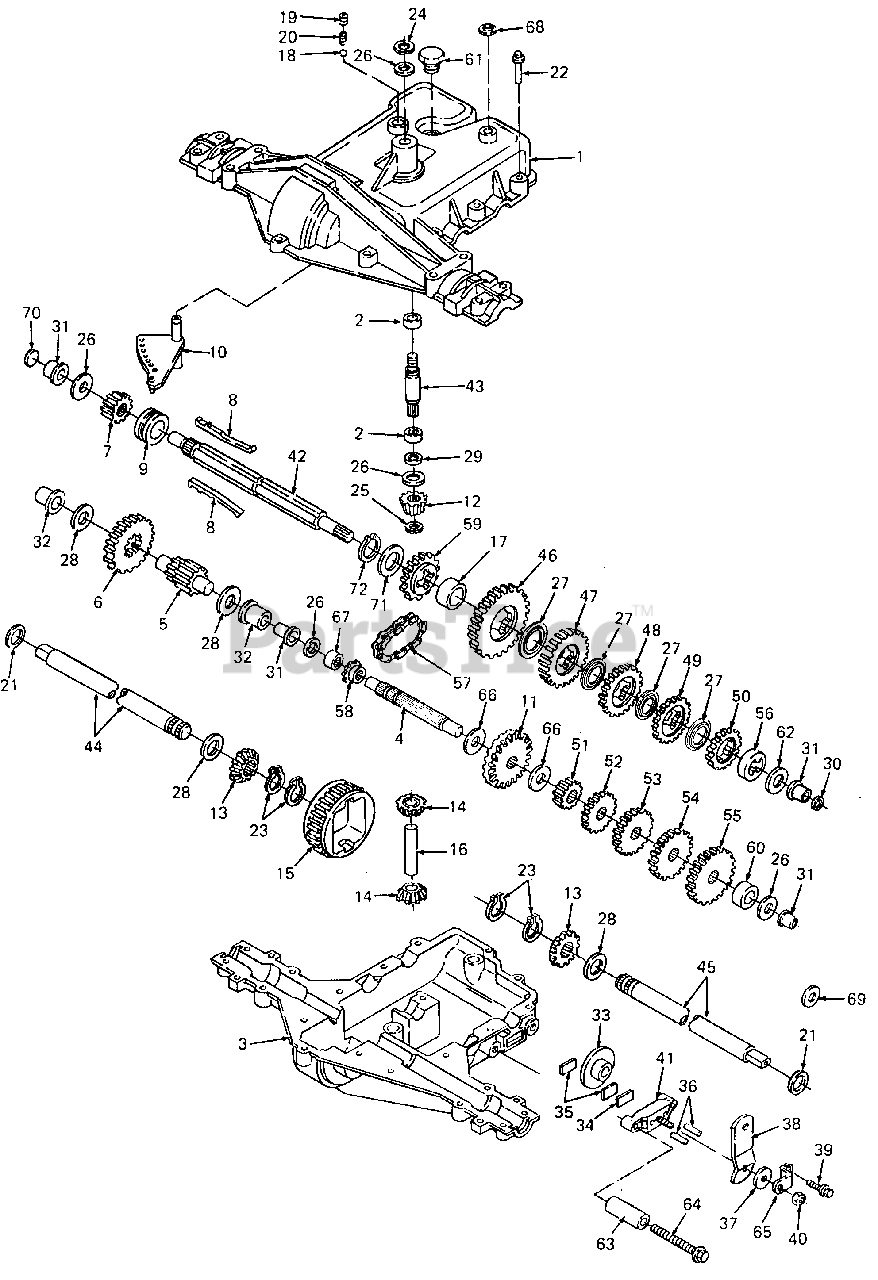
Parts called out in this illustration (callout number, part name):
1	Cover, Transaxle
2	Bearing, Needle
3	Case, Transaxle
4	Shaft, Counter
5	Shaft & Pinion Assy, Output
6	Gear, Output
7	Gear, Spur (15 Teeth)
8	Key, Shifter
9	Collar, Shifter
10	Rod & Fork Assy, Shift
11	Gear, Bevel (42 Teeth)
12	Gear, Bevel Input
13	Gear, Bevel
14	Gear, Bevel Pinion
15	Gear, Ring
16	Pin, Drive
18	Ball, 5/16 Dia, Grade 200
21	Ring, Seal
22	Screw, Flanged Hex, 1/4-20 X 1.25 Lg
23	Ring, Retainer (Set of 2)
24	Ring, Retaining
25	Ring, Ext Ret, .521
26	Washer, Thrust
29	Ring, Quad
30	Ring, Sq Cut
31	Bushing, Flanged
33	Brake, Disc
34	Plate, Brake Pad
35	Pad, Brake
36	Pin, Dowel
37	Washer, Flat, .344 X 1.0 X.063 HDN
38	Lever, Brake
39	Screw, Flanged Hex, 1/4-20 X 1.25 Lg
40	Nut
41	Holder, Brake Pad
42	Shaft, Brake (4-Keyed)
43	Shaft, Input
44	Axle, 11.62 Lg
45	Axle, 16.0 Lg
46	Gear, Spur (37 Teeth)
47	Gear, Spur (30 Teeth)
48	Gear, Spur (25 Teeth)
49	Gear, Spur (22 Teeth)
50	Gear, Spur (20 Teeth)
51	Gear, Spur (12 Teeth)
52	Gear, Spur (20 Teeth)
53	Gear, Spur (25 Teeth)
54	Gear, Spur (28 Teeth)
55	Gear, Spur (30 Teeth)
57	Chain, Roller
58	Sprocket (9 Teeth)
59	Sprocket (18 Teeth)
62	Washer, Thrust
64	Screw, Hex Flanged Hd, 1/4-20 X 2-1/4 Lg
65	Bracket, Brake Lever
66	Washer, Thrust
68	Seal, Sq Cut
70	Disk
71	Washer, Thrust
72	Ring, Retaining
